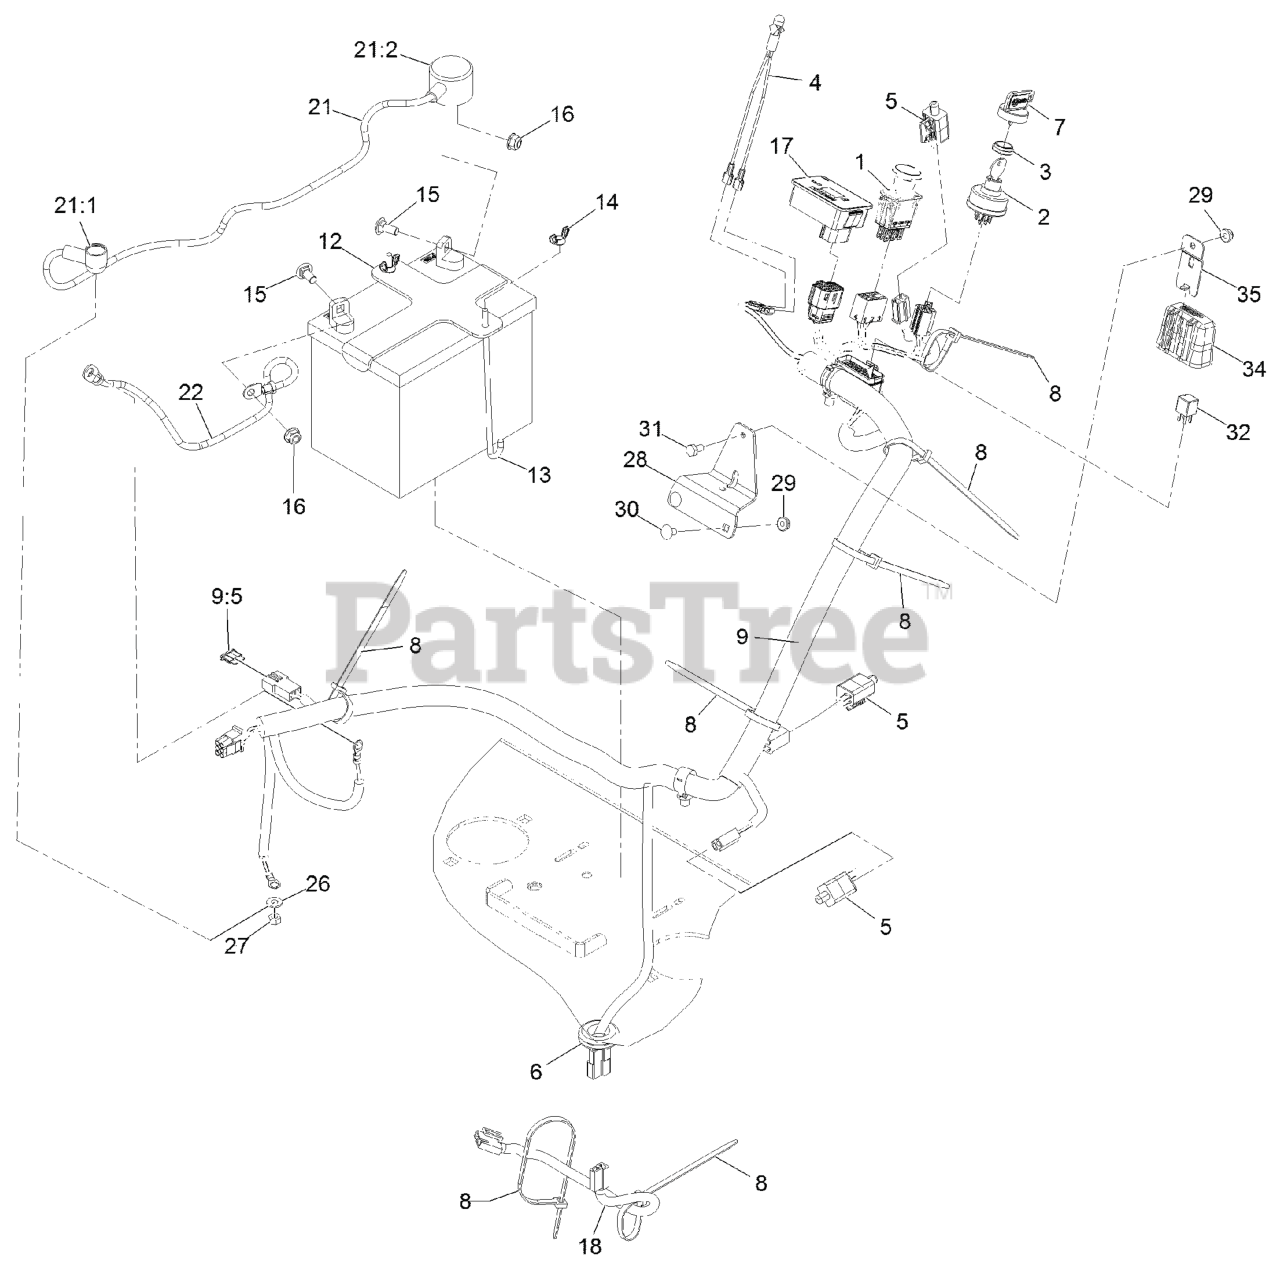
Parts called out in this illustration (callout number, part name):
1	SWITCH-PTO
2	SWITCH, KEY START
3	NUT-SWITCH, IGNITION
4	INDICATOR-LED, RED
6	GROMMET
7	KEY-IGNITION
8	TIE-PLASTIC
9	HARNESS-WIRE
9:5	FUSE-BLADE TYPE, 20 AMP
12	BRACKET, BATTERY HOLD DOW
13	BOLT-HOLDDOWN
14	WINGNUT
15	BOLT-CARR
16	NUT-HF, NI
17	MODULE-HOUR METER
18	HARNESS-CLUTCH PIGTAIL
21	POSITIVE BATTERY CABLE AS
21:1	INSULATOR-SOLENOID
21:2	INSULATOR-BATTERY
26	WASHER-FLAT
27	NUT-HEX
28	BRACKET-MOUNTING, FUSEBLO
30	SCREW-CARR
31	SCREW-HH
32	RELAY-MICRO
34	COVER-BLOCK, FUSE
35	CLIP-MOUNTING
